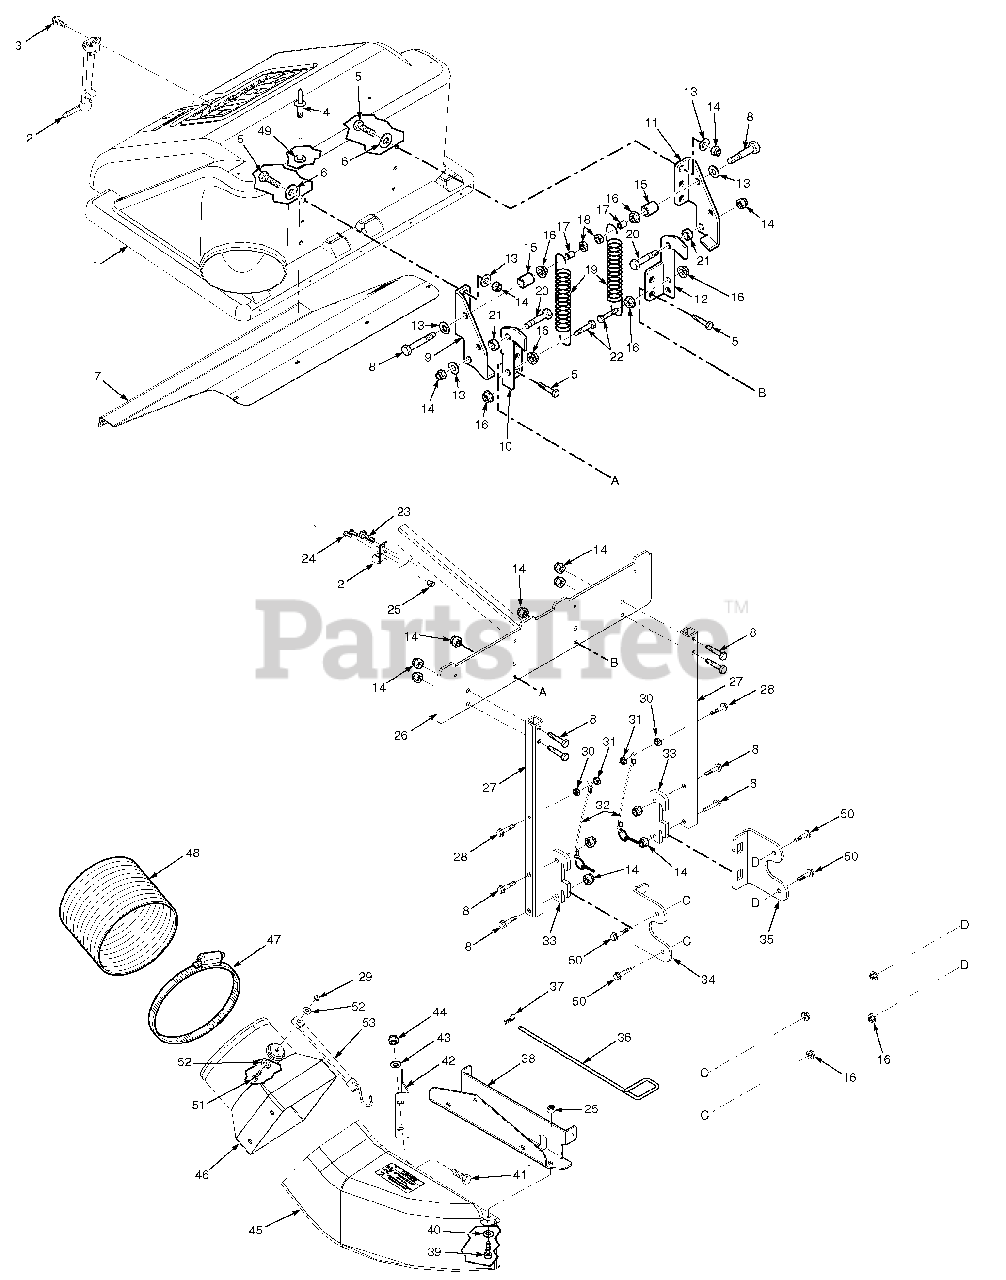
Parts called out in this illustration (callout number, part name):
1	Hood Assembly
2	Latch
3	Screw, #10-32 x 3/4"
4	Pop Rivet, 3/16 x .652
5	Bolt, Hex Head 3/8-16 x 1-1/4"
6	Flatwasher, 3/8-.406 x 1.5 x 7 Ga.
7	Screen, GC Hood
8	Bolt, Hex Head 3/8-16 x 2-1/4"
9	Hinge, Upper RH
10	Hinge, Lower RH
11	Hinge, Upper LH
12	Hinge, Lower LH
13	Flatwasher, 3/8-.391 x .939 x .105
14	Nut, Elastic Stop 3/8-16
15	Spacer
16	Nut, Serrated Flange 3/8-16
17	Sleeve
18	Nut, Center Lock 3/8-16
19	Spring
20	Bolt, Hex Head 3/8-16 x 1-1/2"
21	Bushing, Hopper Pivot
22	Bolt, Hex Head 3/8-16 x 1-3/4"
23	Bolt, Hex Head 5/16-18 x 3/4"
24	Pop Rivet, 3/16 x .402
25	Nut, Elastic Stop 5/16-18
26	Frame Weldment, Bag Support
27	Tube, Grass Catcher Mount
28	Bolt, Hex Head 1/4-20 x 2"
29	Nut, Elastic Stop 1/4-20
30	Nut, Serrated Flange 1/4-20
31	Nut, Center Lock 1/4-20
32	Quick Pin Assembly
33	Latch, GC-SFZ
34	Bracket, GC Mount RH
35	Bracket, GC Mount LH
36	Latch Pin, GC Chute
37	Hair Pin Cotter
38	Bracket, GC Boot
39	Bolt, Hex Head 5/16-18 x 1"
40	Flatwasher, 5/16-.344 x .688 x .065
41	Bolt, Hex Head 1/4-20 x 1"
42	Baffle, Boot Deflector
43	Flatwasher, 1/4-.312 x .750 x .065
44	Nut, Elastic Stop 1/4-20
45	Boot Assembly
46	Adapter w/Strap
47	Clamp, 8.62" Max Dia.
48	Hose, 8" x 56"
49	Flatwasher, 3/16-.196 x .469 x .048
50	Bolt, Hex Head 3/8-16 x 1"
51	Bolt, Hex Head 1/4-20 x 1-1/4"
52	Flatwasher, 1/4-.312 x .750 x .065
53	Rubber Strap
